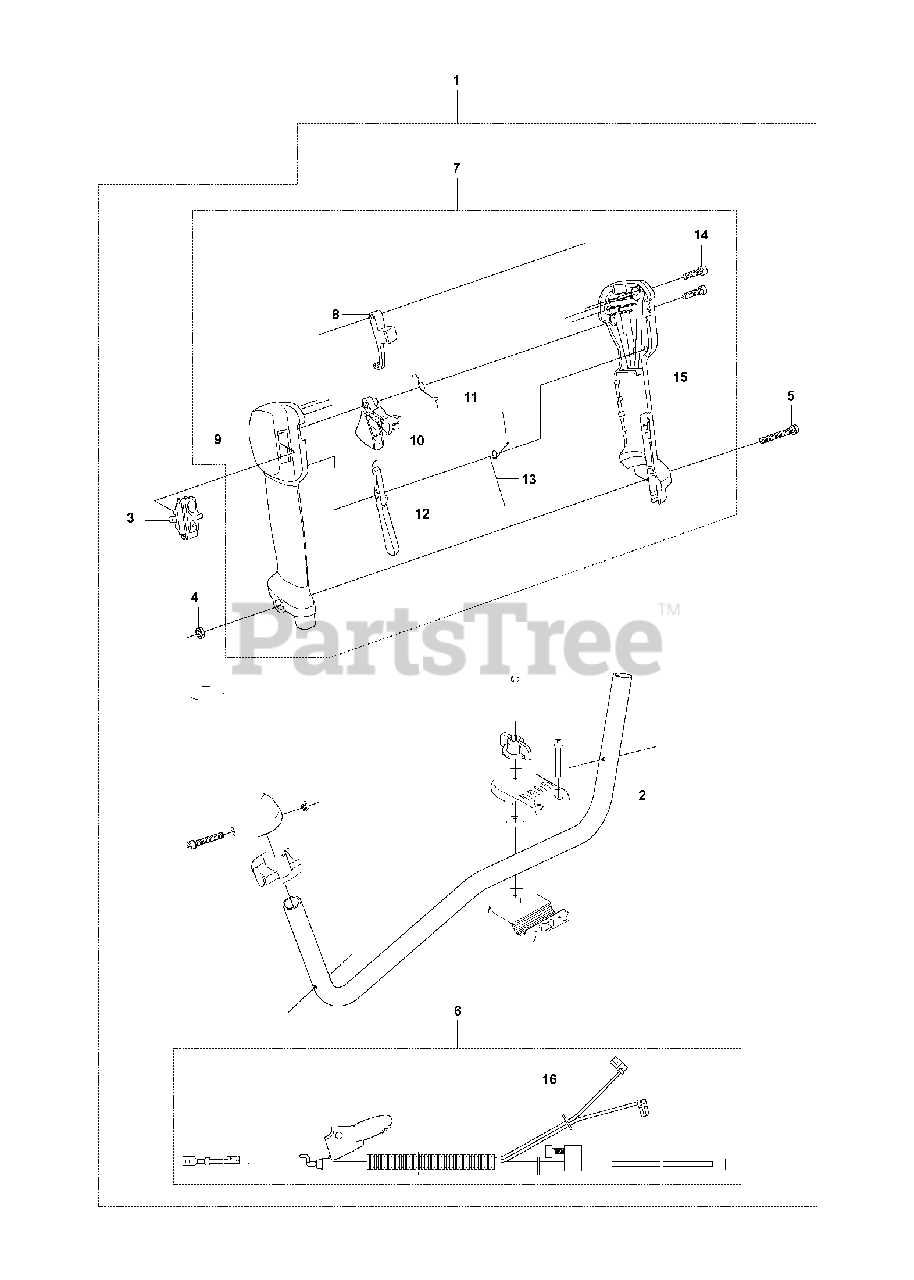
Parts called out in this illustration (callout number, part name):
2	HANDLE
4	NUT
5	%SCREW
6	WIRING ASSY
8	SWITCH
9	HANDLE HALF LEFT
10	TRIGGER
11	SPRING
12	TRIGGER SAFETY
13	SPRING
14	SCREW
16	SCREW
